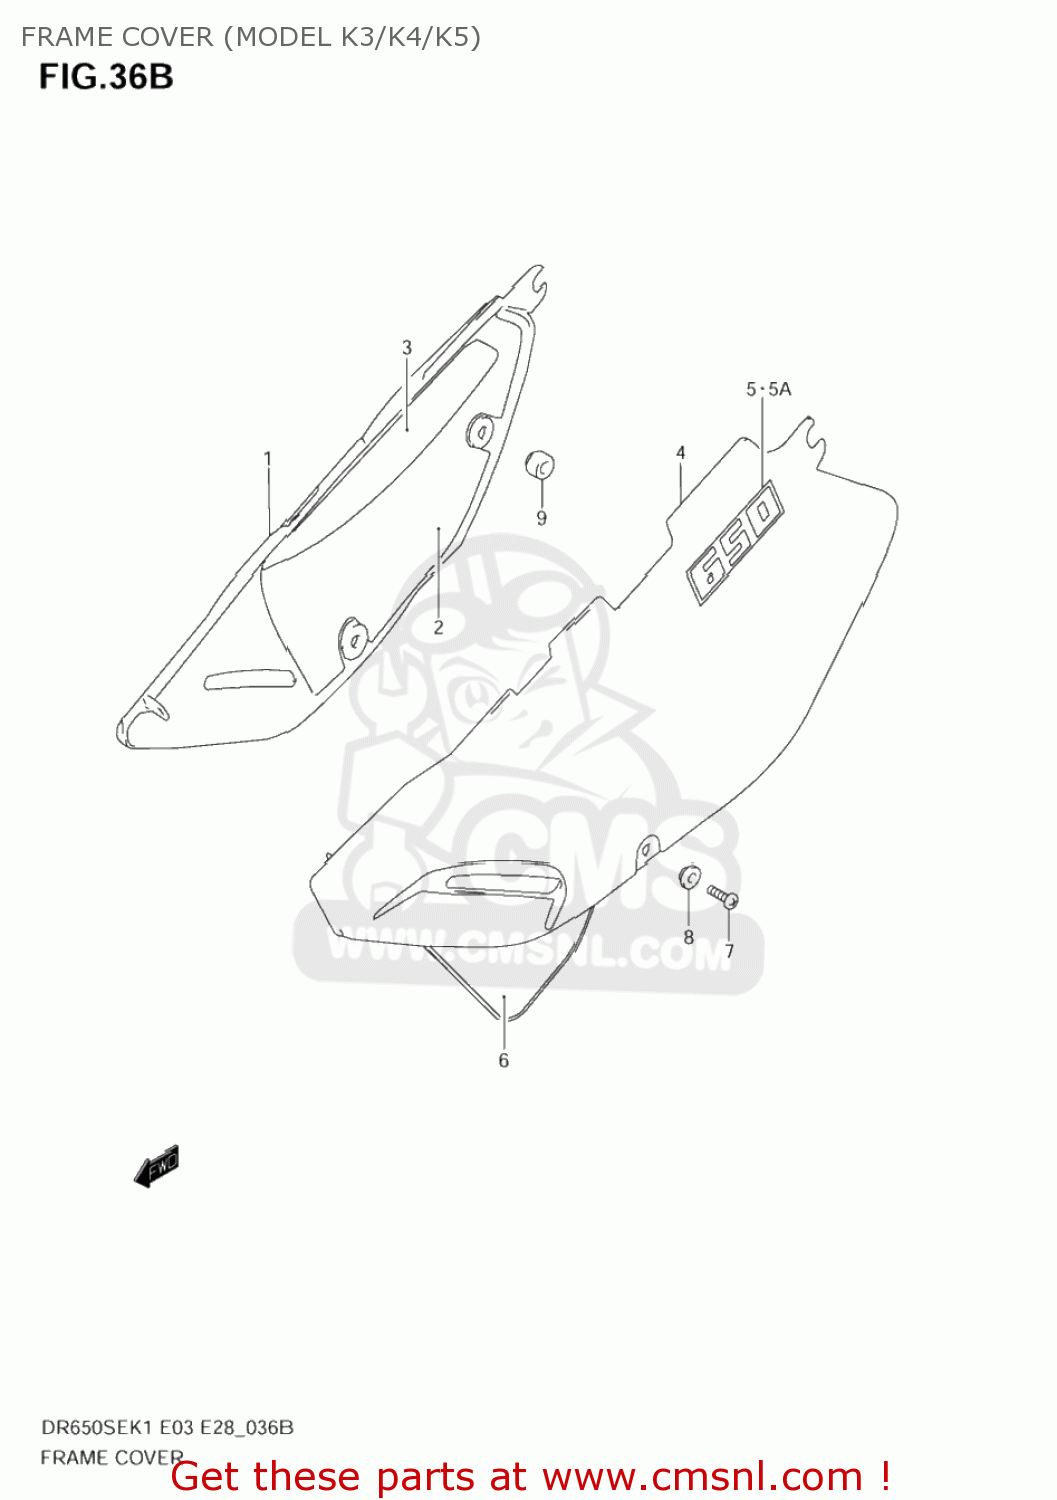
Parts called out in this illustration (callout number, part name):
1	COVER,FRAME,RIGHT
2	SHIELD,FRAME COVER,R NO.1
3	SHIELD,FRAME COVER,R NO.2
4	COVER,FRAME,LEFT
5	EMBLEM,FRAME COVER
5A	EMBLEM,FRAME COVER
6	TAPE,LWR
7	SCREW
8	WASHER
9	CUSHION
